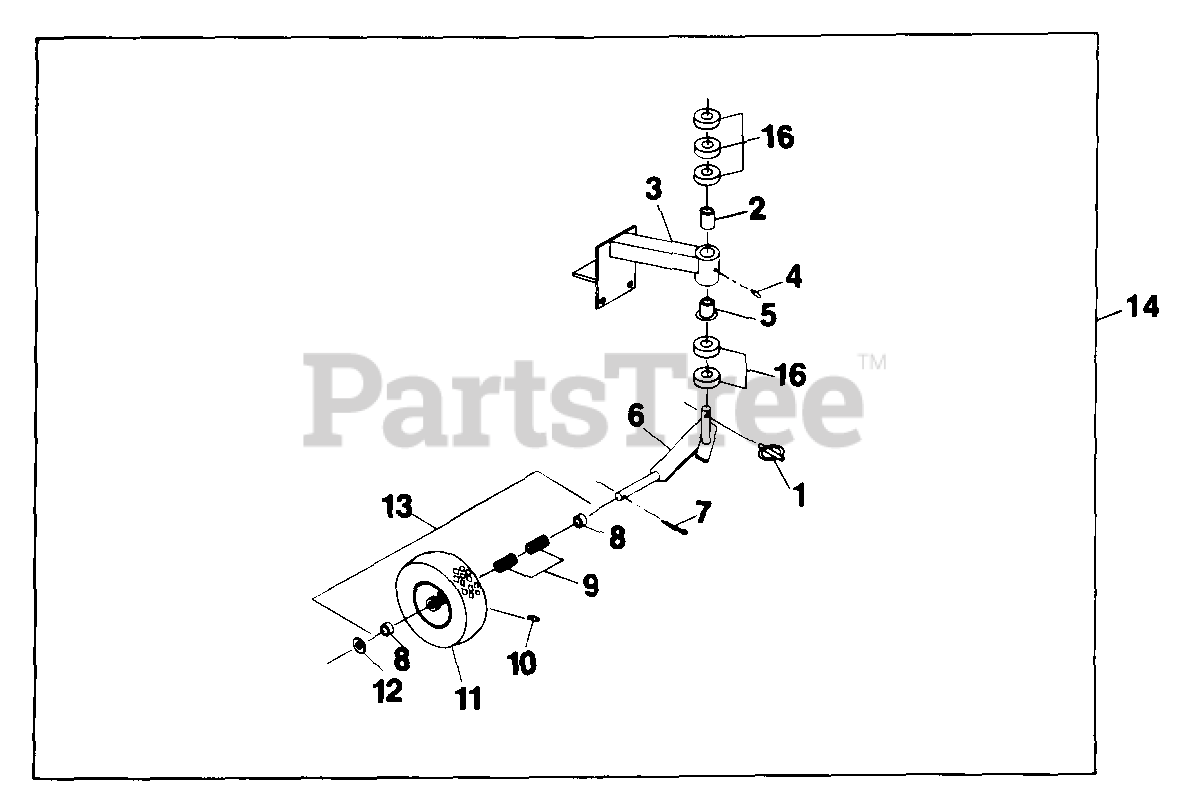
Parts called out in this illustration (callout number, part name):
2	BEARING,STRAIGHT
6	WLD,CASTER STRUT
16	SPACER-CASTER
